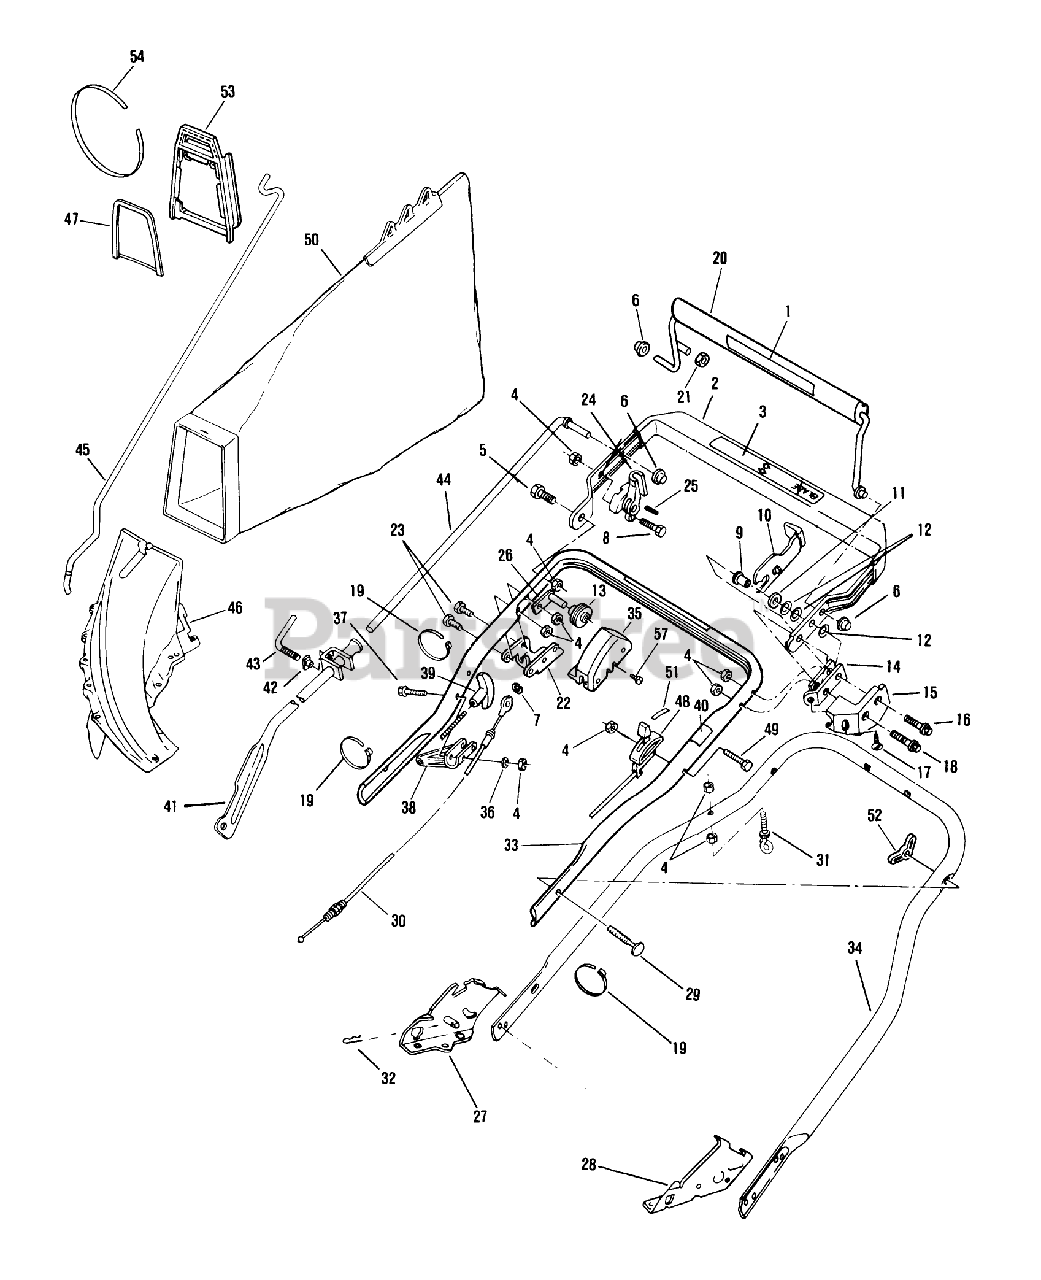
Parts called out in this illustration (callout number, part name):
4	LOCKNUT E
5	BOLT
7	RET. RING
9	SPACER
11	WASHER M
13	PULLEY PL
14	DOWN STOP
15	LOCKOUT GUARD
16	BOLT SHOU
17	SCREW F
18	SCREW
21	NUT ACORN
24	CAM HOFFER
27	BRACKET ASM - HANDLE, SP, RH
28	BRACKET ASM - HANDLE, SP, LH
29	BOLT QUALITY
30	CONTROL CABLE
31	EYE BOLT WAS MFG
32	HAIR PIN
36	WASHER
39	HANDLE START UM&D
41	CONTROL LEVER AY
44	CONTROL ROD
45	ROD GRASSBAG
47	CHUTE BRACE
48	CONTROL THROT WES
50	ORDER 89816 THRU WHOLE GD
52	NUT-WING
53	CHUTE - ADAPTER
57	7011 21 LB MOWER O/
